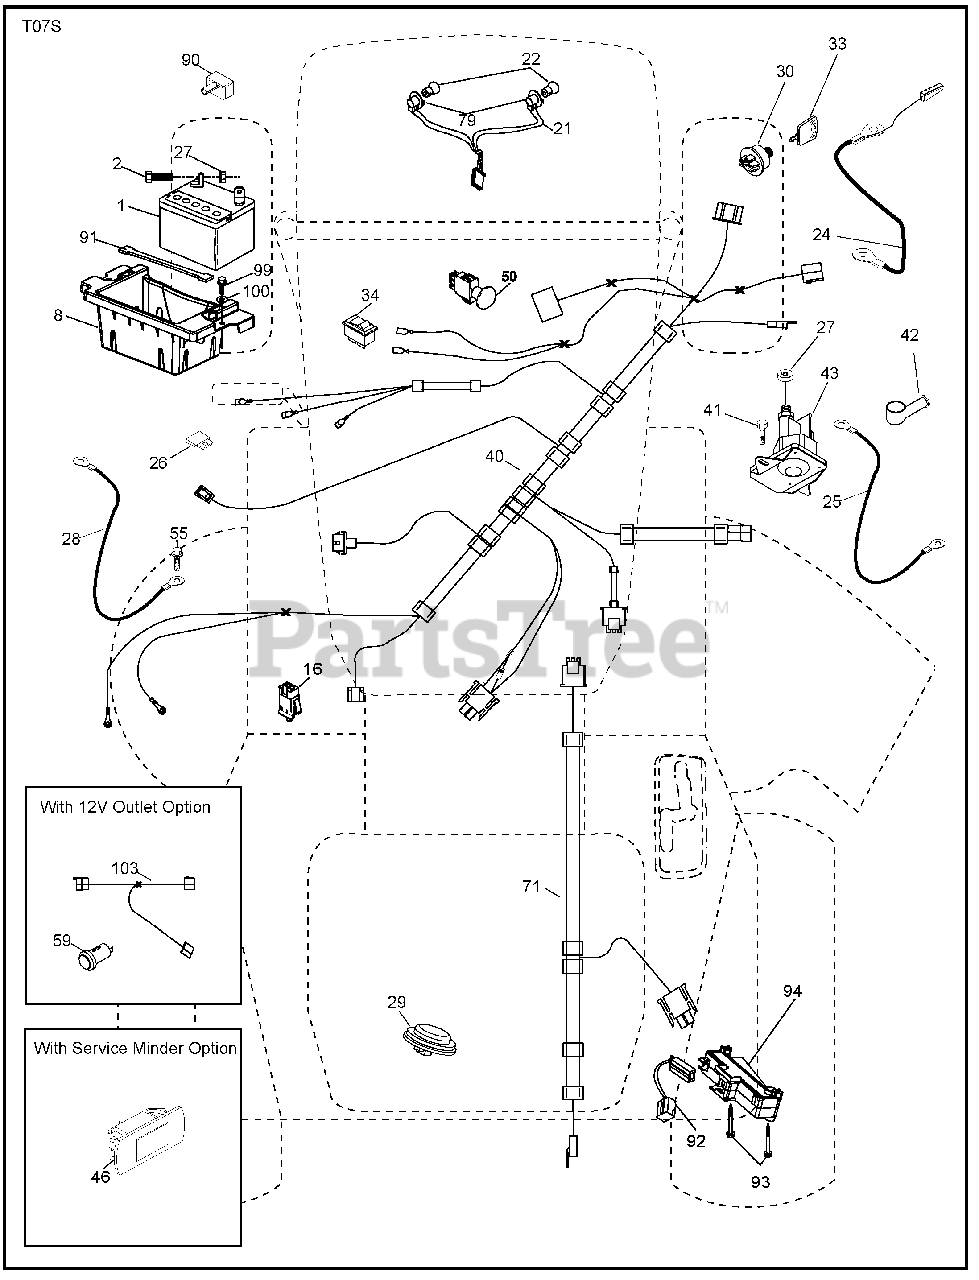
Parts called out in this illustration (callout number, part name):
1	Battery
2	Bolt Hex Hd 1/4-20 unc x 3/4
8	Battery Box
16	Switch Interlock
21	Harness Socket Light
22	Bulb, Light # 1156
24	Cable Battery
25	Cable Starter
27	Nut Keps Hex 1/4-20 unc
28	Cable Ground 21" Blk 6 Ga.
29	Switch Seat
30	Switch Ign
34	Switch Light/Reset
40	Harness Ign. Dash
41	Screw Thd Cut 1/4-20 x 1/2
42	Cover Terminal Red
43	Solenoid
46	Gauge Hourmeter
50	Switch PTO
55	Screw Thdrol 5/16-18 x 3/4
59	Outlet 12-Volt
71	Harness Ign
79	Socket Asm Bulb Twistlock
90	Cover Terminal Battery
91	Strap Battery
92	Harness Pigtail Console ROS
93	Screw Plastite 10-14 x 2.0
94	Module Reverse ROS
99	Screw Hexwsh Thdrol 1/4-20 x 3/4
100	Washer 9/32 x 7/8 x 16 Ga.
103	Harness Pigtail 12V Outlet
